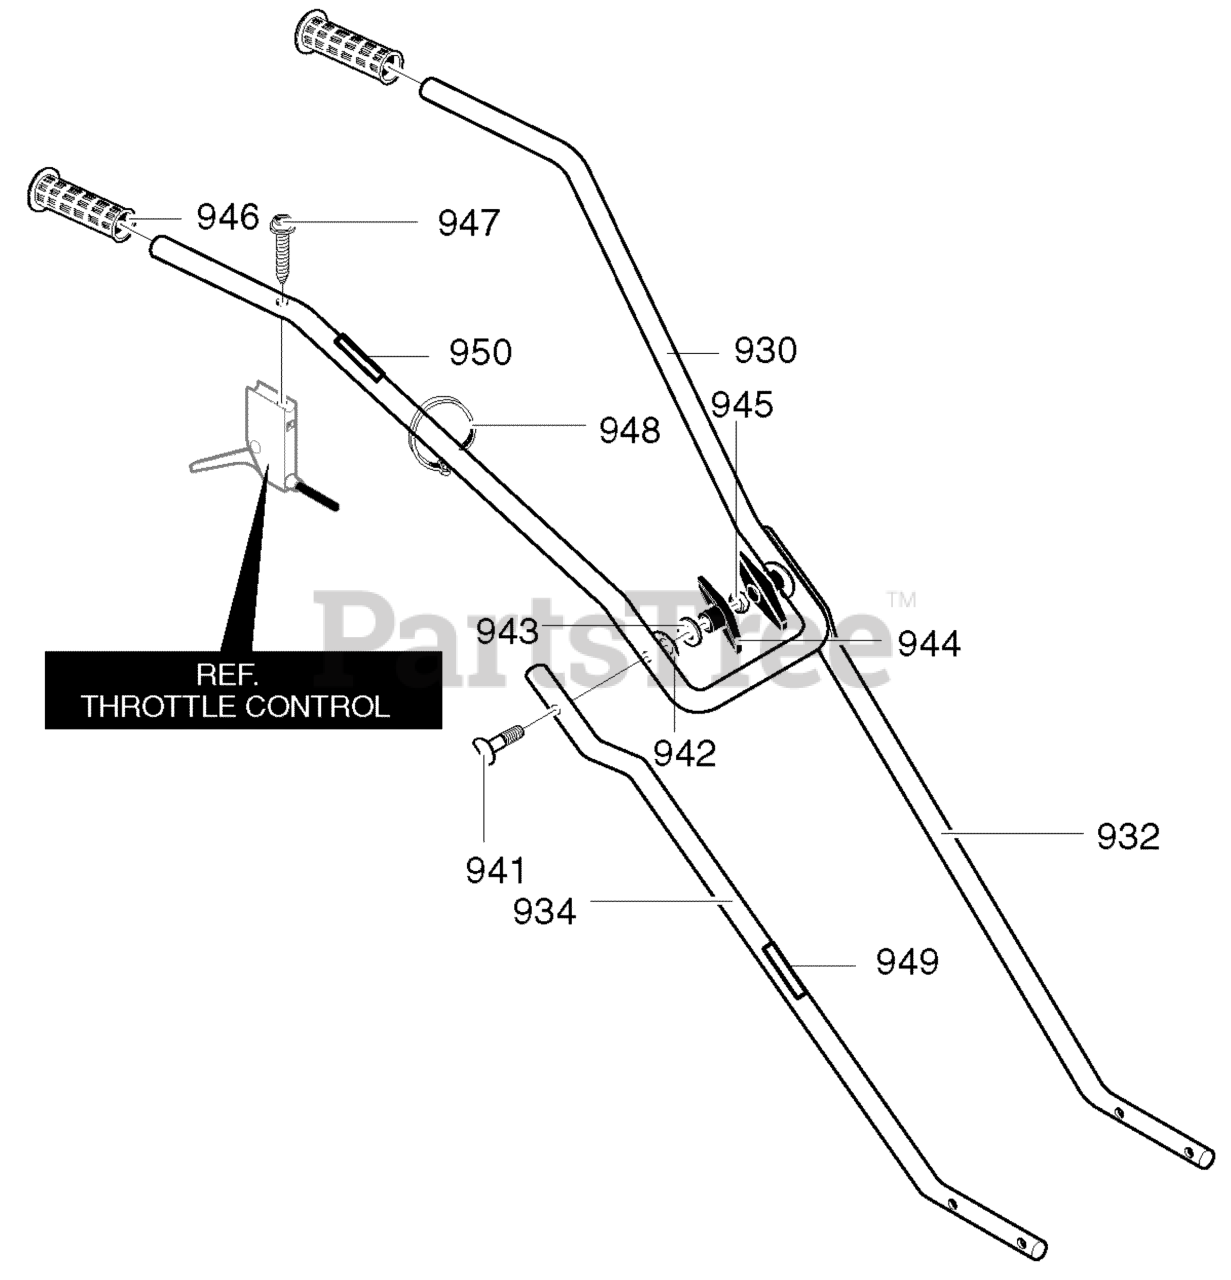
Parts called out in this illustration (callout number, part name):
930	Upper Handle
932	Lower Handle LH
934	Lower Handle RH
941	Bolt 5/16-18x1.75
942	Formed Washer
943	Flat washer
944	T Knob
945	Nut, 5/16-18
946	Hand Grip
947	Screw, 10-16x1.50
948	Cable Tie
949	Decal, Caution (Starting)
950	Decal, Throttle Control
